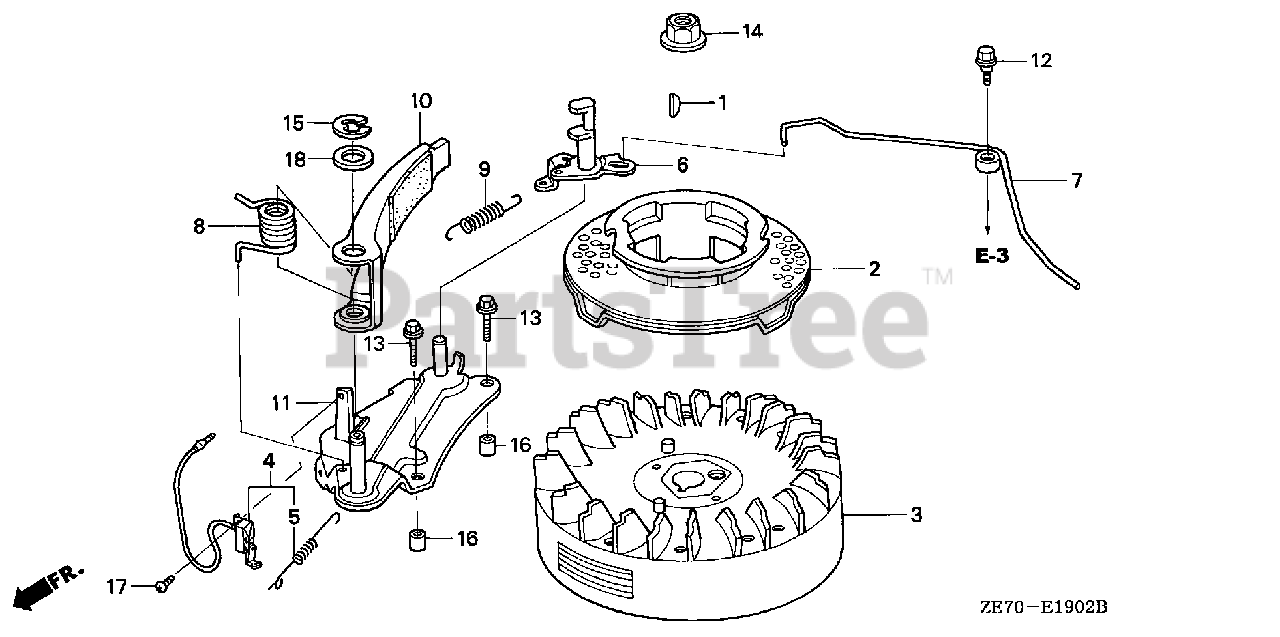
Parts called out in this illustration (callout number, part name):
1	KEY, SPECIAL WOODRUFF (25X18)
2	PULLEY, STARTER
3	FLYWHEEL (BAND BRAKE)
4	SWITCH ASSY., ENGINE STOP
5	SPRING, SWITCH CONTROL
6	CAM, BRAKE
7	ROD, THROTTLE RETURN
8	SPRING, BRAKE
9	SPRING, BRAKE RETURN
11	BASE, BRAKE
12	BOLT, FLANGE (6MM)
13	BOLT, FLANGE (6X23) (CT200)
14	NUT, SPECIAL (14MM)
15	E-RING (10MM)
16	PIN, DOWEL (8X9)
17	SCREW, PAN (4X8)
18	WASHER, PLAIN (12MM)
